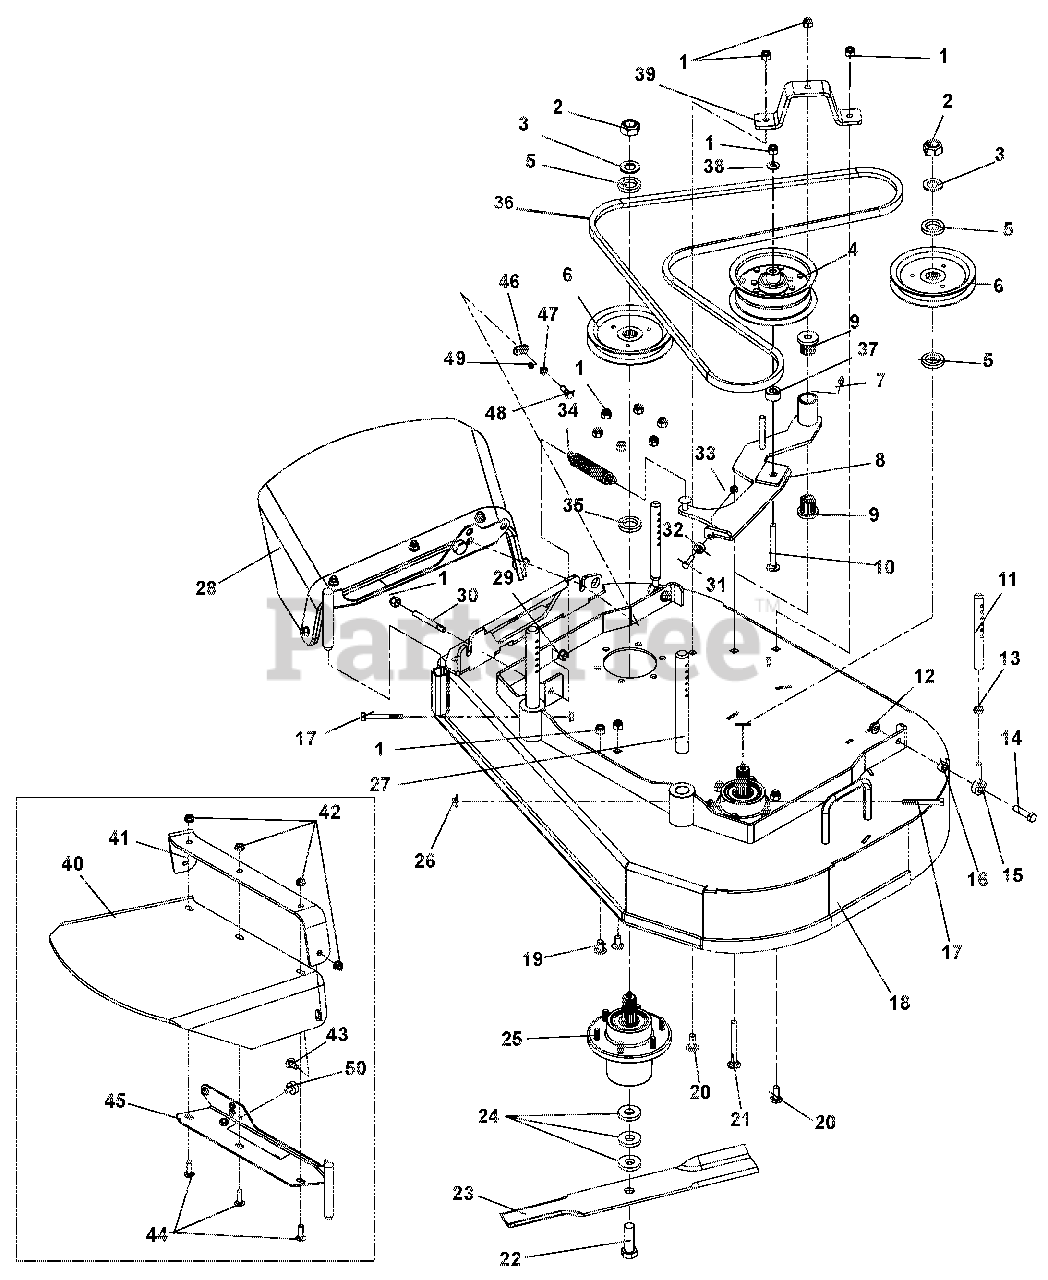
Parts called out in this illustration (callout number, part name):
1	NUT-LK-NYL .38-16
2	LOCKNUT, 3/4-16 CROWN GR 5
3	WASHER, .75 X 1.3125 X .113
4	PULLEY, FLAT 5.00 X 2.36 X .375
5	WSHR, FL-STL 1.0 X 1.5 X .25
6	PULLEY, SPLINE SPINDLE SHFLWLK
7	FTG, 1/4-28 STRGT GREASE ZERK
8	WLDT, IDLER ARM 36
9	BRG, FLG M10 X M25 X M27 FLUTED
10	BOLT, RDHDSQNK .38-16X3.50 GR5Y
11	ROD, REAR HOC
12	NUT, LK TOP FLG .375-16 YWZC REV
13	NUT, JAM .375-24 YWZC REV
14	BOLT, HEX .38-16 X 1.50 GR5
15	ROD, END 3/8 RH REV
16	BSHG - SLV REV
17	BOLT, 5/16-18X2.50 HEX 8
18	ASSY, 36" FLWLK DECK W/DECALS
19	BOLT, RDHDSHSQNK .38-16 X .75 G5
20	BOLT, RDHDSQNK .38-16X1.00 G5
21	BOLT, RDHDSQNK .38-16X3.50 GR5
22	BLT-HEX .62-11X 2.00 GR8 YWZC
23	BLADE, 18"
24	WASHER, FLAT-STEEL .630 x 1.50 x .25
25	ASSY, SPINDLE HOUSING
26	NUT-SPNLK-FLG .312-18
27	PIN, HOC
28	ASSY, DISCHARGE SHIELD
29	NUT-SPNLK-FLG .375-16
30	ROD, THREADED ADJUSTMENT
31	BOLT, HEX .25-20 X 1.00 GR5
32	BRG, BAL .250 X .688 X .313
33	NUT-LK-NYL .250-20
34	SPRING, EXT .875 X .125 X 4.25 Y
35	SPACER, 1.500 X 1.000 X .510 Y
36	BELT, HB 85.1 EL AMD
37	SPACER, .437 X 1.00 X .58 SMLS
38	WASHER, .406 X .813 X .065 FLAT Y
39	STRAP, IDLER 36
40	SHIELD, WALK RUBBER DISCHARGE
41	STRAP, GRAVELY WLK RUBBER DIS
42	NUT, SPNLK-FLG .375-16
43	BOLT, RDHDSQNK .38-16 X 1.00 G5
44	BOLT, RDHDSQNK .38-16 X 1.25 G5
45	WLDT. DISCHARGE
46	KEEPER, BOLT
47	WSHR-LK-EXT.391X.628X.036YWZC
48	BLT,HEX.38-16X1.25 GR5 CAPTIVE
49	RVT-POP .187 YZ
50	BUMPER, RUBBER
